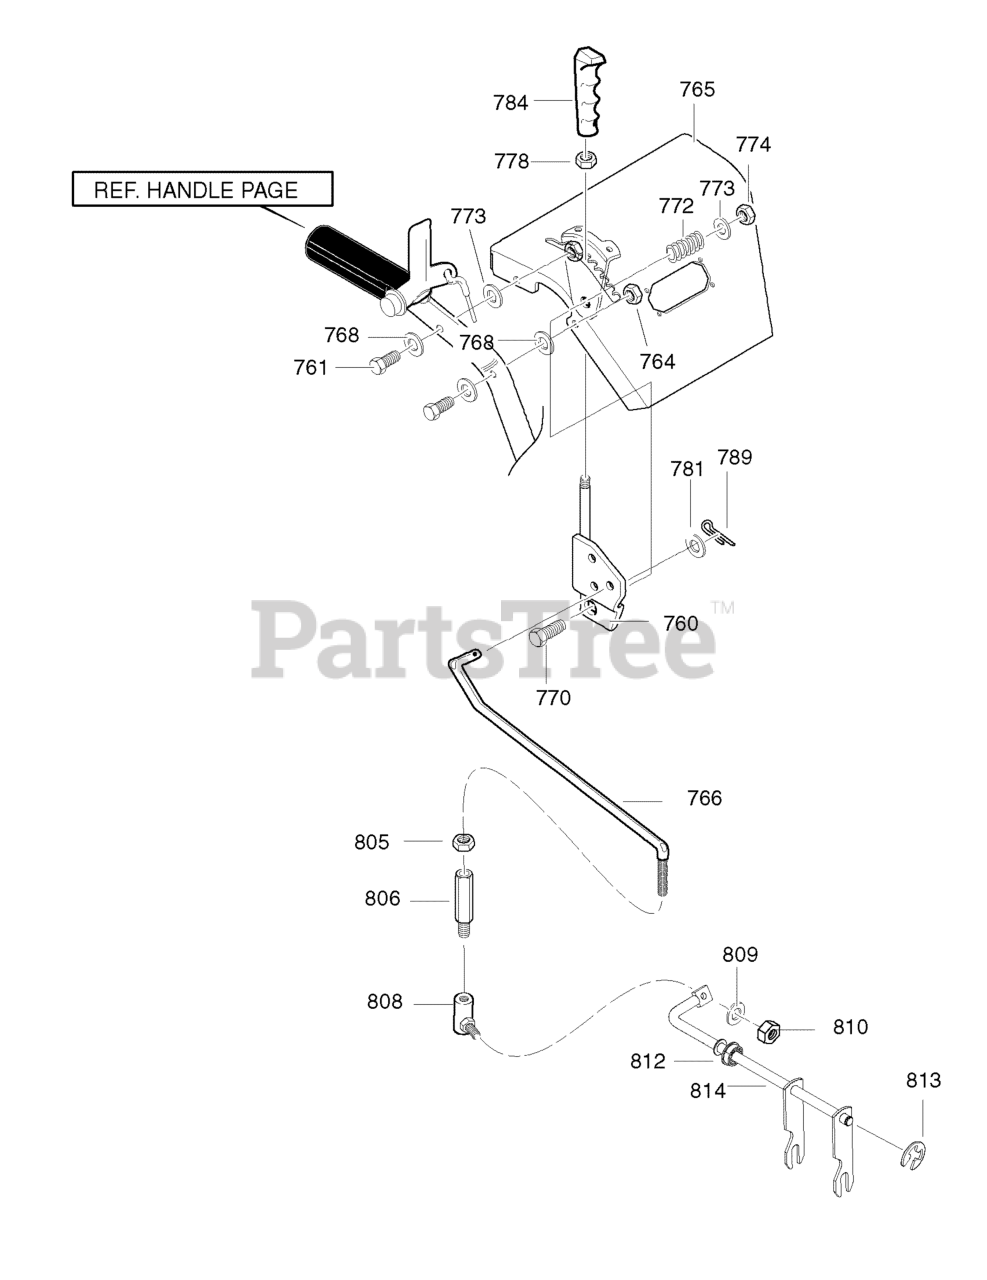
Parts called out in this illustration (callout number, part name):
760	ASSEMBLY, HANDLE SPEED CONTROL
761	SCREW, 5/16-18 x 1.75
764	NUT, 5/16-18
765	ASSEMBLY, BAY PANEL - LT
766	ROD, SPEED CONTROL
768	WASHER
770	SCREW 3/8-16X2.00
773	WASHER, Flat, 13/32
774	NUT, 3/8-16
778	NUT, 3/8-16
781	FLATWASHER
784	HANDLE, GRIP
789	PIN, COTTER
805	NUT, 5/16-18
806	ADAPTER, SPEED ROD -YZ
808	BALLJOINT, STEEL -YZ
809	WASHER
810	NUT, 5/16-18
812	BEARING, FLANGE
813	RING, RETAINER
814	ROD, ASSY YOKE
